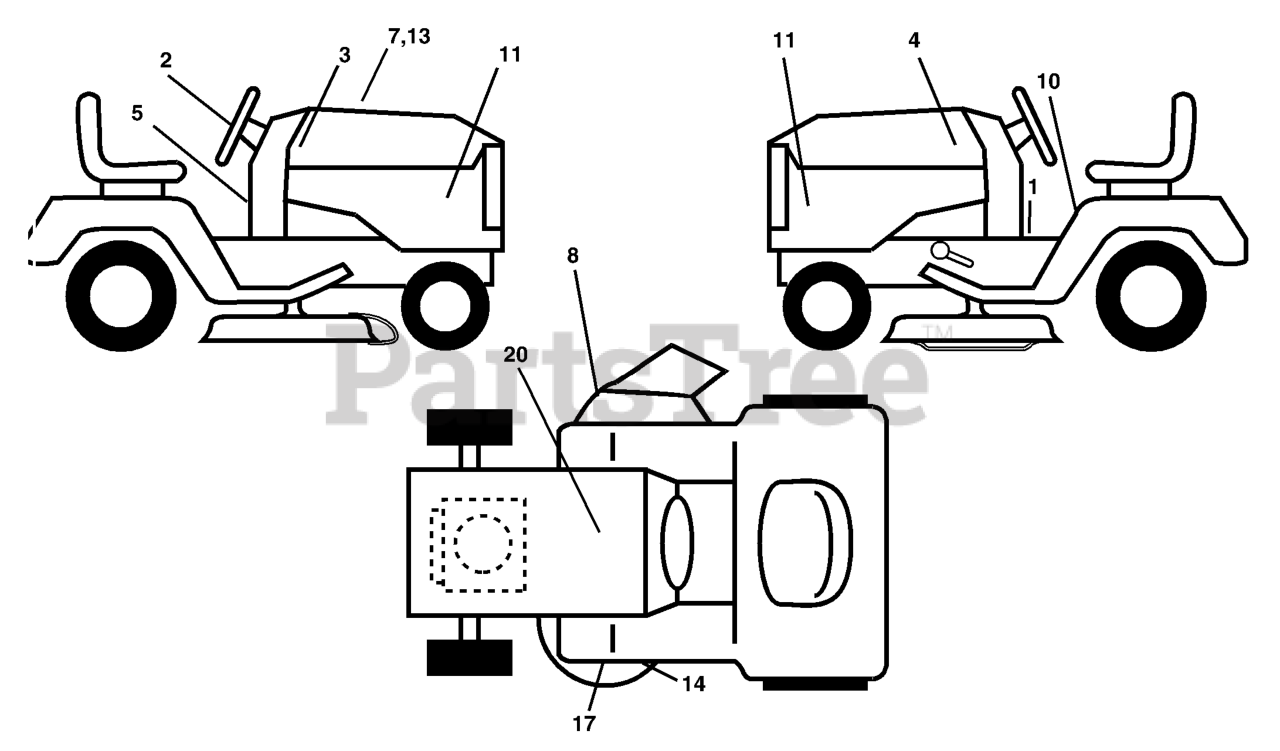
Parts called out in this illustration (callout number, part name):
2	DECAL.STEERING.HUSQ.BLUE
3	DECAL, HOOD RH
4	DECAL, HOOD LH
8	DECAL.WARN.KEEP.HAND.AWAY
10	DECAL FENDER DANGER
11	DECAL HOOD SIDES
13	DECAL HOOD CUST. RESP.
14	DECAL V-BELT SCHEMATIC
17	DECAL, MOWER HEAVY DUTY
20	DECAL BTRY SYMBOLS
